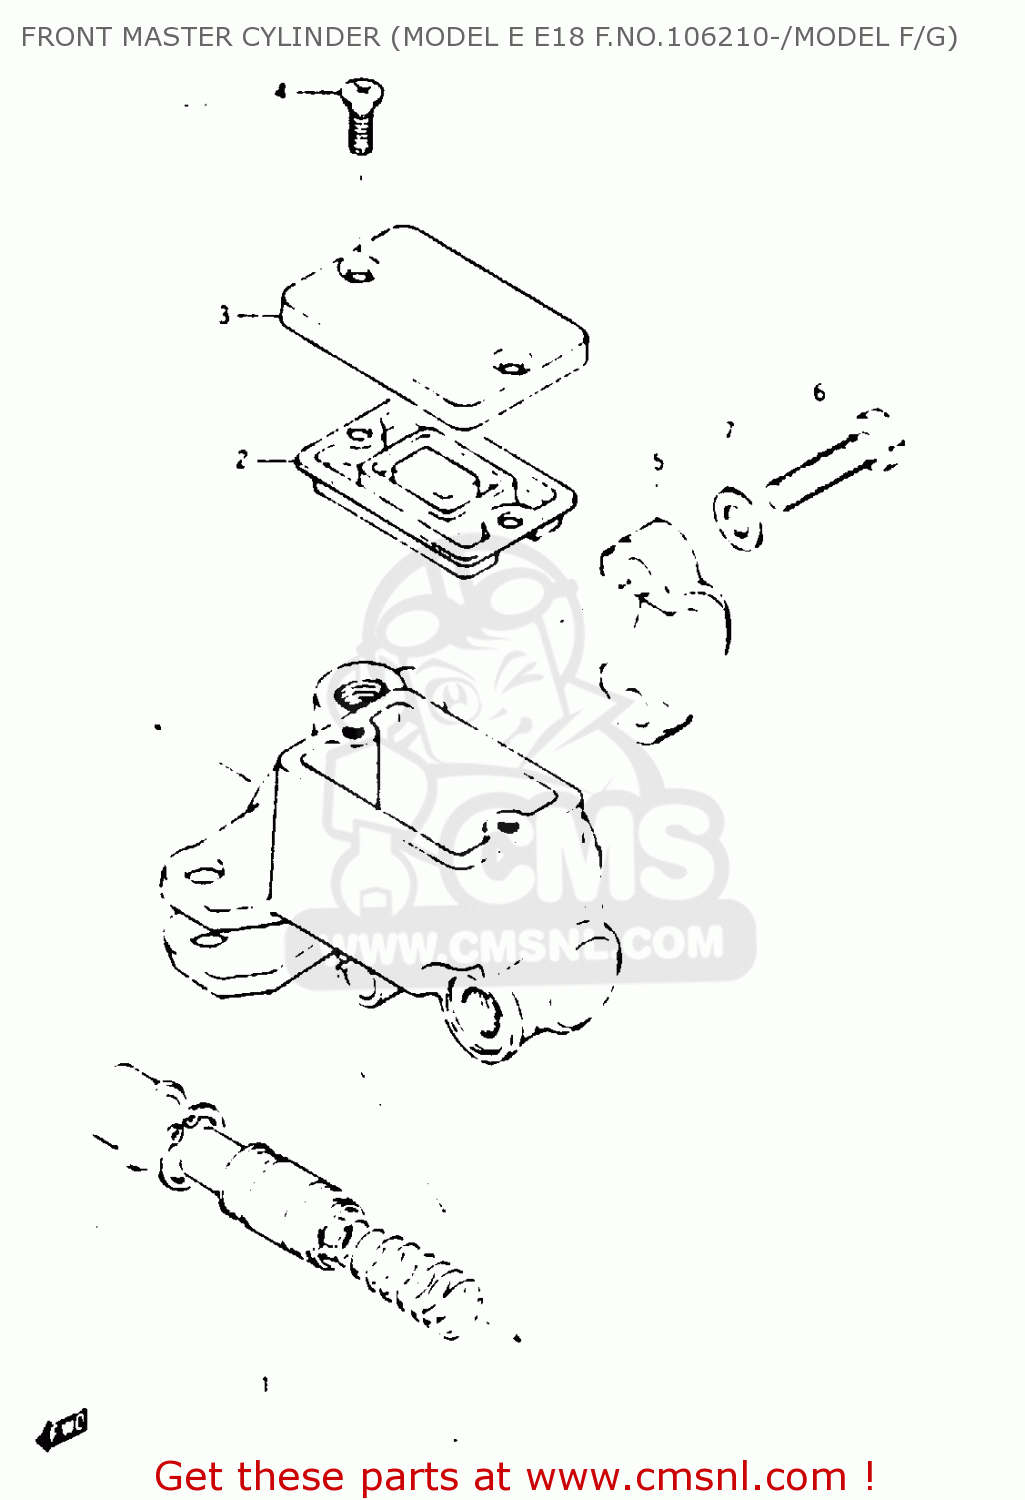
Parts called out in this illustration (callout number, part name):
1	PISTON/CUP SET
2	DIAPHRAGM
3	CAP
4	SCREW
5	HOLDER
6	BOLT
7	WASHER
